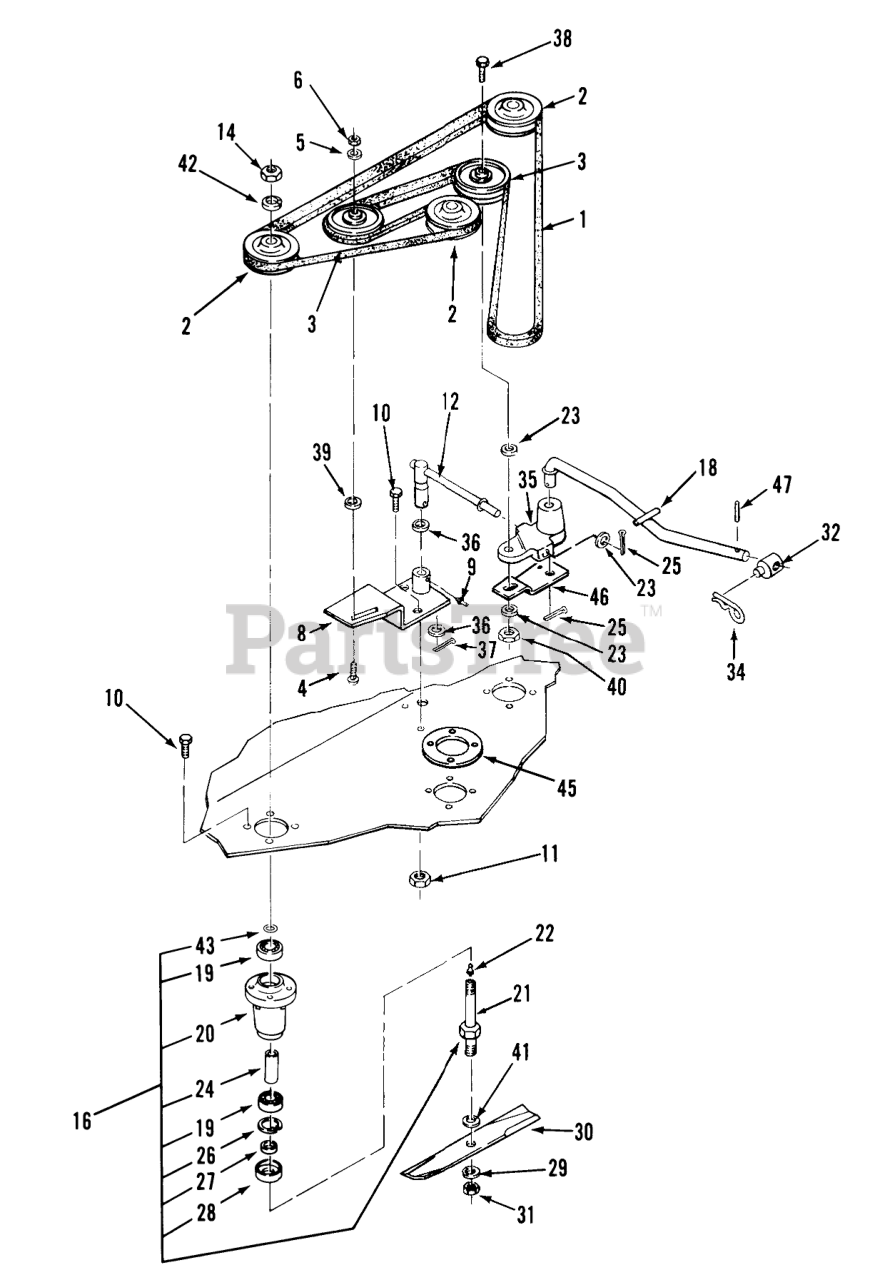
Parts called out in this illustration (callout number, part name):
1	BELT-MOWER
2	PULLEY-BLADE
3	PULLEY-FLAT IDLER
4	Bolt-Carriage
5	Washer
6	NUT
8	ASS'Y-IDLER BRKT R(NS)
9	FITTING-GREASE
10	Bolt
11	NUT
12	ASS'Y-IDLER ARM B
14	Nut
16	Spindle Assembly (Includes items 19 thru 22, 24, 26 thru 28 & 43)
18	ASS'Y-ROD IDLER
19	BEARING-BALL
20	HOUSING-SPINDLE
21	SHAFT-SPINDLE
22	Zerk
23	Washer
25	Pop Rivet
26	Ring-Snap
27	SPACER-BLADE
28	CUP-SPINDLE
29	Washer
30	S/A BLADE KIT
31	Nut-Jam
32	TRUNNION-LIFT
34	Hairpin Cotter
35	BLOCK IDLER
36	WASHER
37	Cotter Pin
38	Bolt
39	PAD-SHORT R
40	NUT
41	Washer
42	Lockwasher
43	O RING
45	PLATE-SPINDLE
46	ANCHOR-SPRING B
47	Pin-Roll
